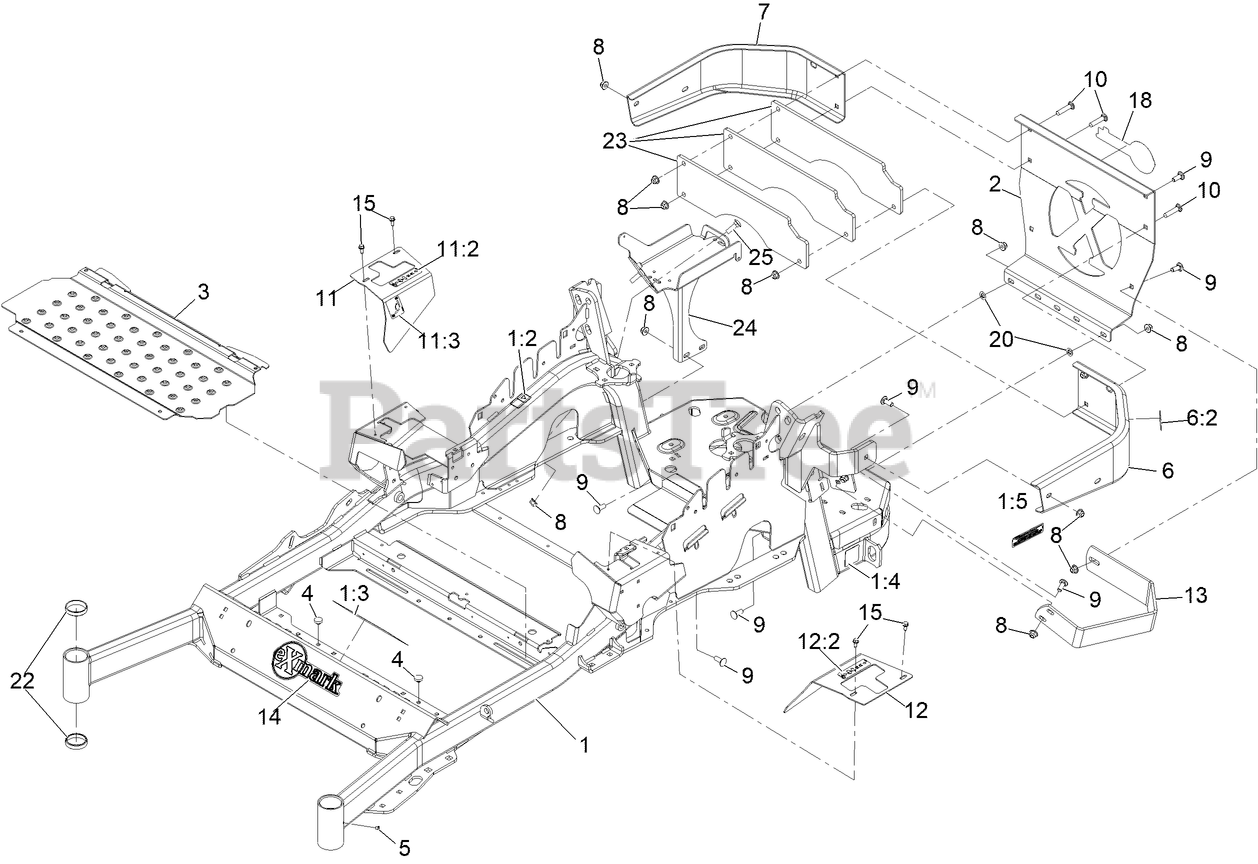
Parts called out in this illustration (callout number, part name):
1	Mainframe ASM - Rd
1	Mainframe Service ASM -Rd
1:2	DECAL-WARNING
1:3	DECAL-DANGER
1:4	DECAL-HAZARD, PINCHED FINGER
1:5	DECAL-ARRESTOR, SPARK
2	PLATE,REAR GUARD
6	LH BUMPER ASM
6:2	DECAL-WARNING
7	BUMPER-RH
8	NUT-HF, NI
9	SCREW-CARR
10	SCREW-CARR
11	RH MOTION CONTROL COVER ASM
11:2	DECAL-CONTROL, MOTION
11:3	DECAL-PARK BRAKE, CE
12	LH MOTION CONTROL COVER ASM
12:2	DECAL-CONTROL, MOTION
13	GUARD-MUFFLER
14	DECAL-EXMARK
15	SCREW-HWH
18	DECAL, EXMARK LOGO
20	NUT-PUSH
22	CUP-BEARING
23	PLATE-WEIGHT, 6 LB
24	BATTERY MOUNT ASM
25	BOLT-CARR
